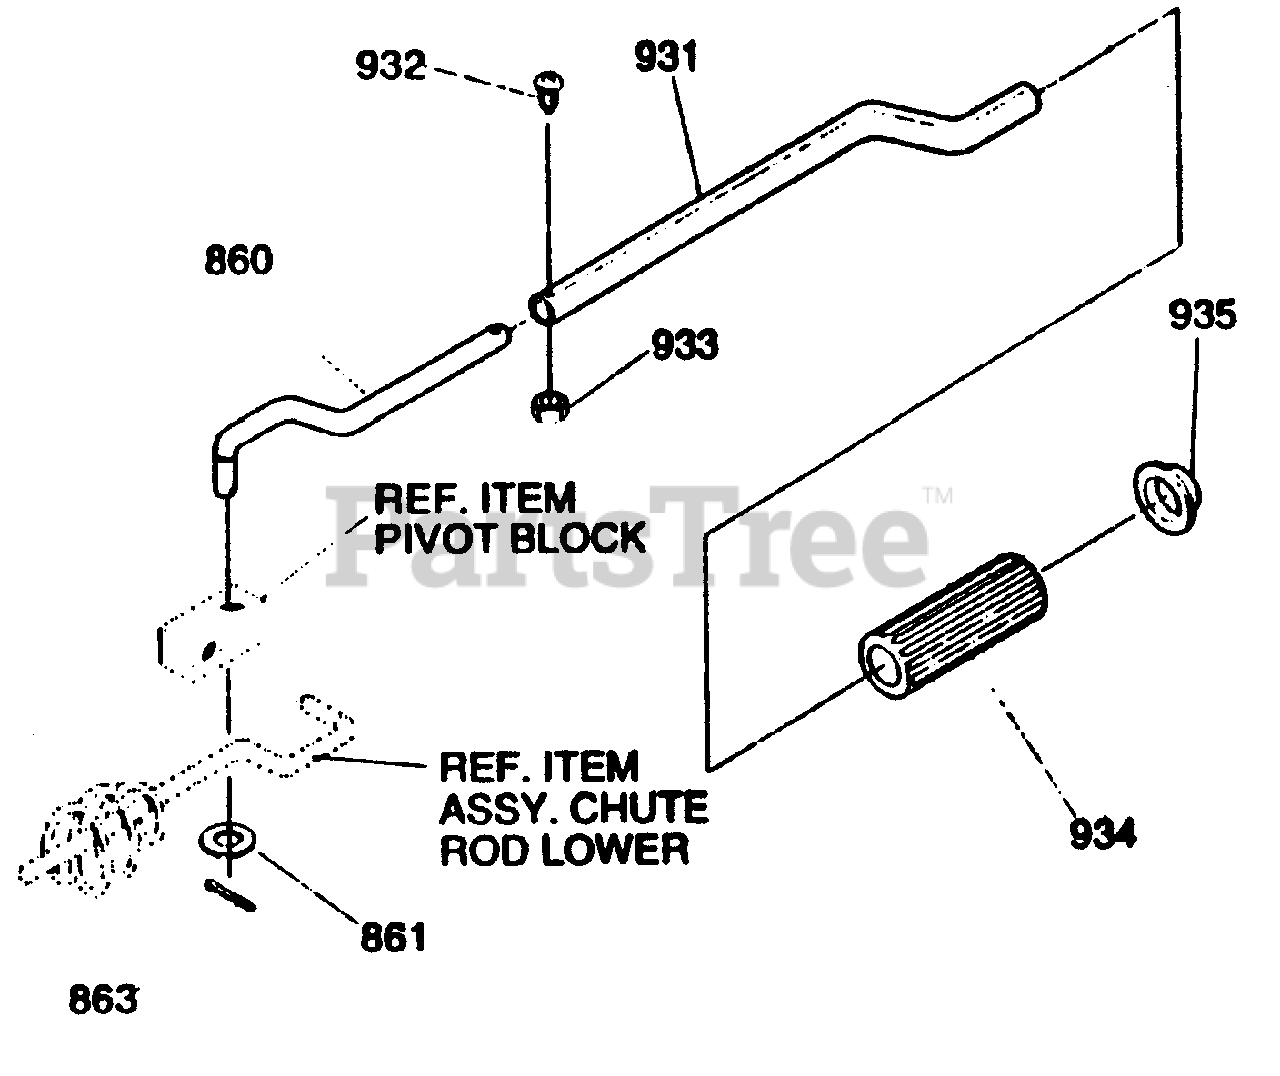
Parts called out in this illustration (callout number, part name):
860	ROD, MID CHUTE CTL
861	WASHER, FLAT .40 X .75X.025
863	PIN, COTTER .080 DIAX .75LG
931	ROD CHUTE CTRL UPR, ASSY
932	SCREW, 10-32X .88 SLTRHD
933	NUT, #10-32 CTRLK
934	KNOB, CHUTE CRANK
